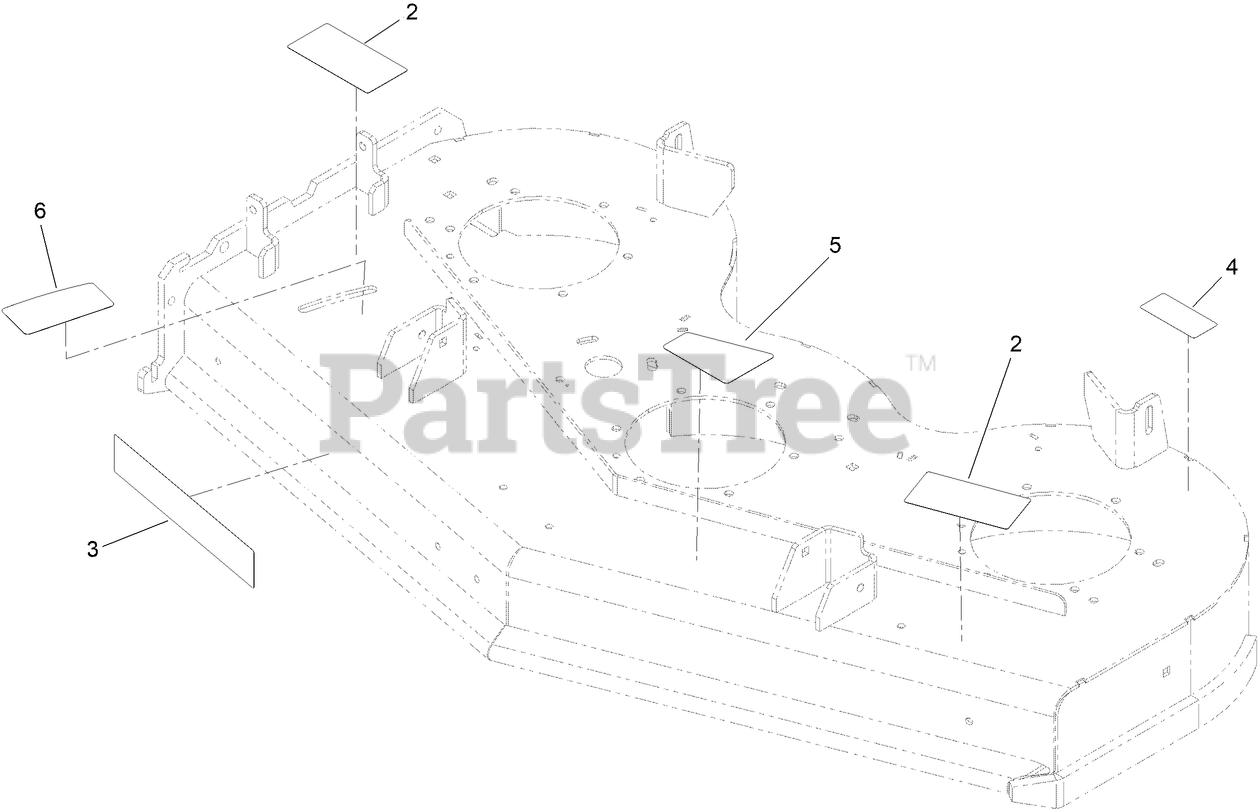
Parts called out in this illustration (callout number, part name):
2	DECAL-DANGER
4	DECAL-BOLT TORQUE
5	DECAL-BELT, TENSION (CE)
6	DECAL - BAFFLE ADJUSTMENT
